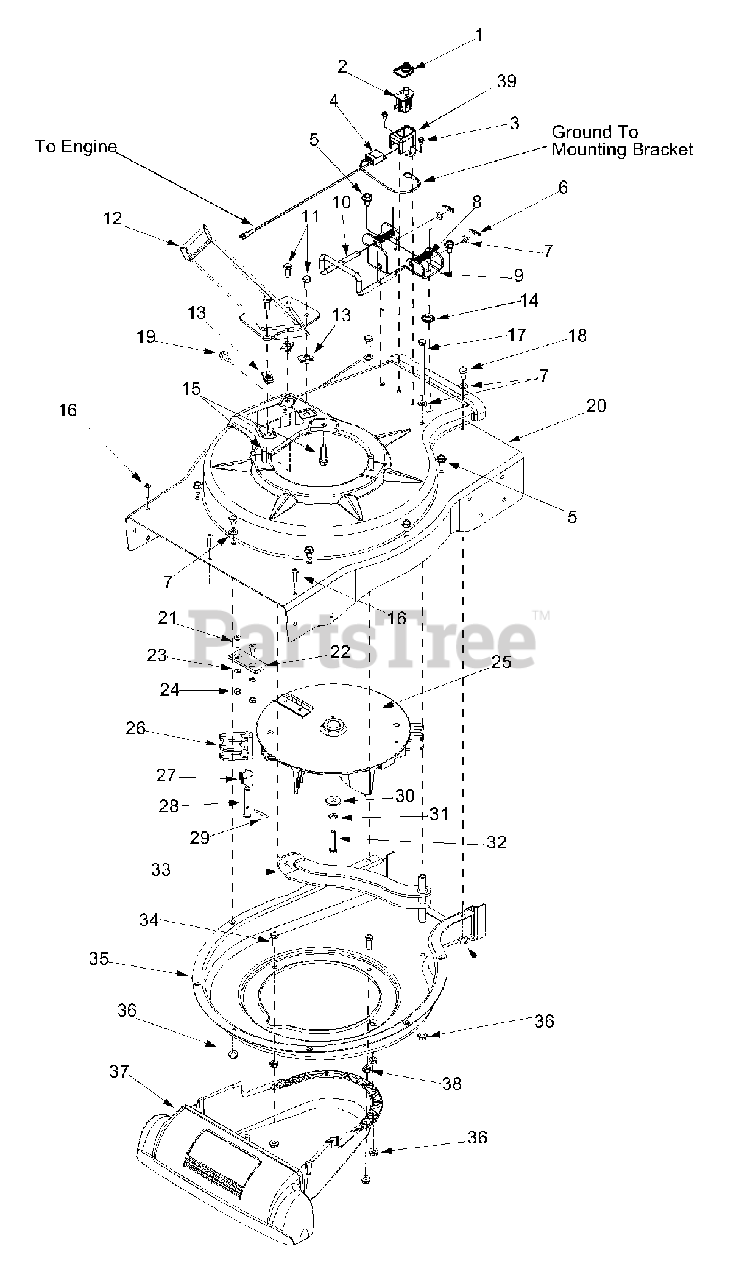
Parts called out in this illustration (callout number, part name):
1	Switch Cover
2	Safety Switch
3	Hex Washer Screw #10-16 x .50
4	Wire Harness
5	Hex Washer Screw 5/16-18 x .625
6	Cotter Pin
7	Flat Washer.330 ID x.630 OD
8	Compression Spring
10	Lock Rod
11	Hex Cap Screw 5/16-18 x .75
13	U-Clip Lock Nut 5/16-18
14	External Lock Washer 5/16
15	Hex Washer Screw 3/8-16 x 1.25
16	Screw #12-16 x 1.0
17	Hex Cap Screw 5/16-18 x 4.5
18	Hex Cap Screw 5/16-18 x .625
19	Hex Washer Screw 5/16-18 x .625
22	Chipper Blade
23	Lock Washer 5/16
24	Hex Lock Nut 5/16-24
25	Impeller Assembly
26	Flail Blade
27	Pin Clip
28	Clevis Pin
29	Spiral Pin
30	Flat Washer.375 ID x 1.25 OD
31	Lock Washer 3/8
32	Hex Cap Screw 3/8-24 x 2.0
34	Hex Cap Screw 5/16-18 x .875
36	Lock Nut 5/16-18
37	Nozzle Cover
38	Lock Nut 5/16-18
39	Safety Switch Cover
